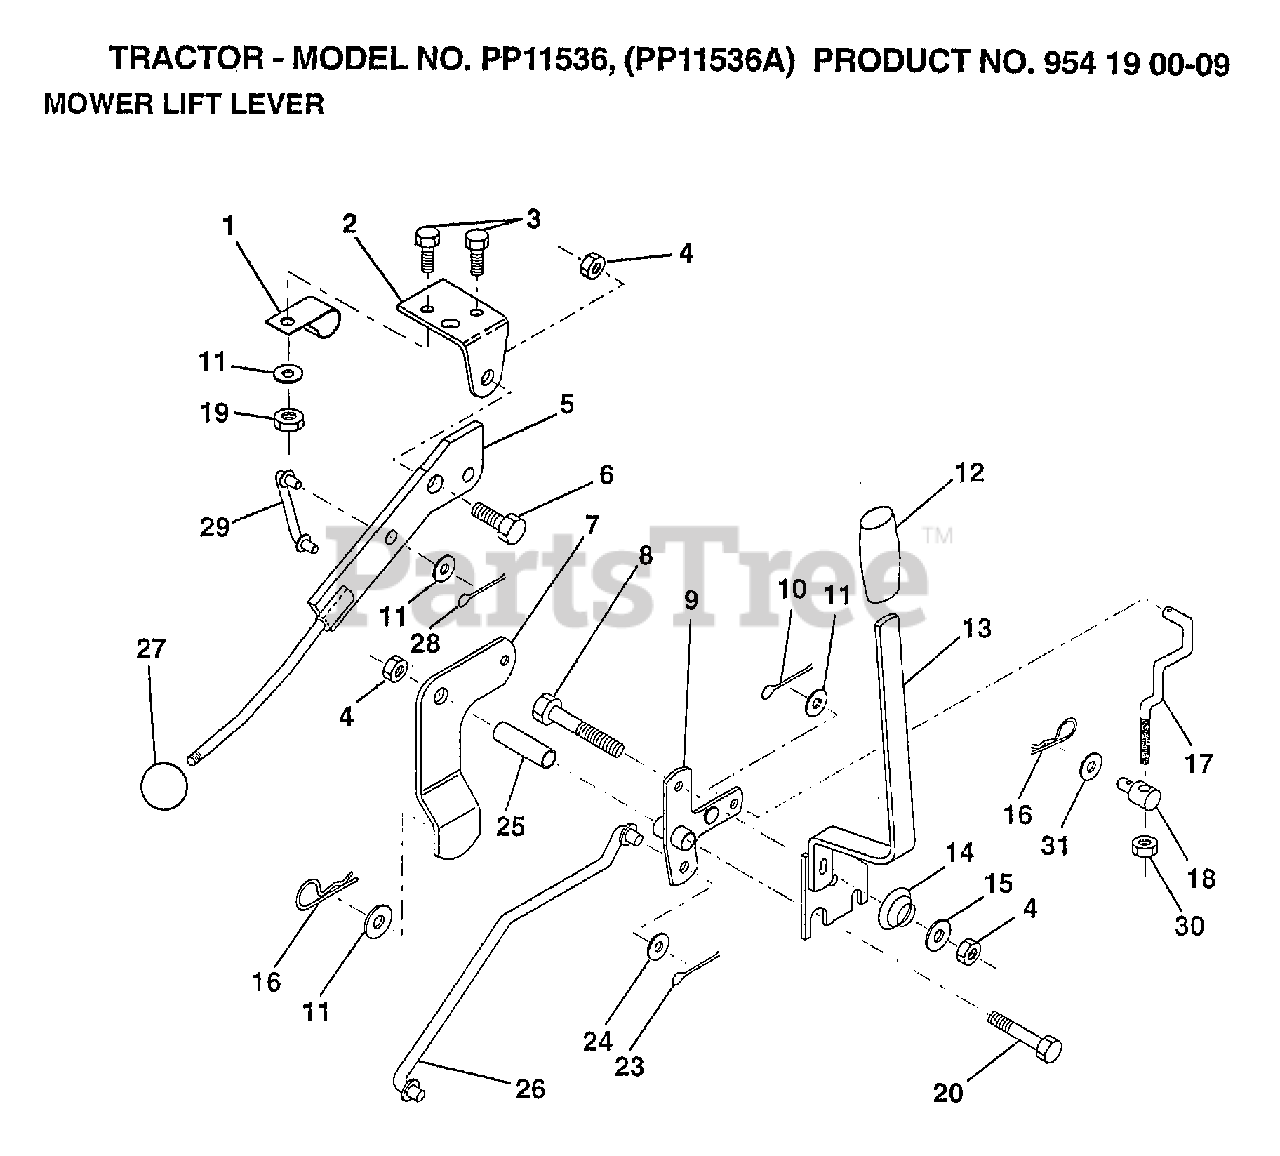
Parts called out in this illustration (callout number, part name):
1	"CLIP,INSULATOR"
2	BRKT CLUTCH
3	BOLT HXHD FIN
5	LEVER.ASM.CLUTCH
6	"BOLT, SHOULDER LT"
7	MWR CLUTCH ARM AS
8	BOLT
9	"BELLCRANK,LIFT"
10	COTTER PIN
11	WASHER
13	HANDLE.ASM.LIFT
14	SPRING COMPRESSIO
15	WASHER T
16	SPRING.RETAINER
17	"LINK,LIFT FRT"
18	TRUNION ADJ
20	BOLT
23	PIN COTTER 1/8
25	TUBE SPACER
26	ROD LIFT MOWER
27	KNOB T(3/8 HOLE)
29	CLUTCH LINK
30	NUT
31	WASHER
